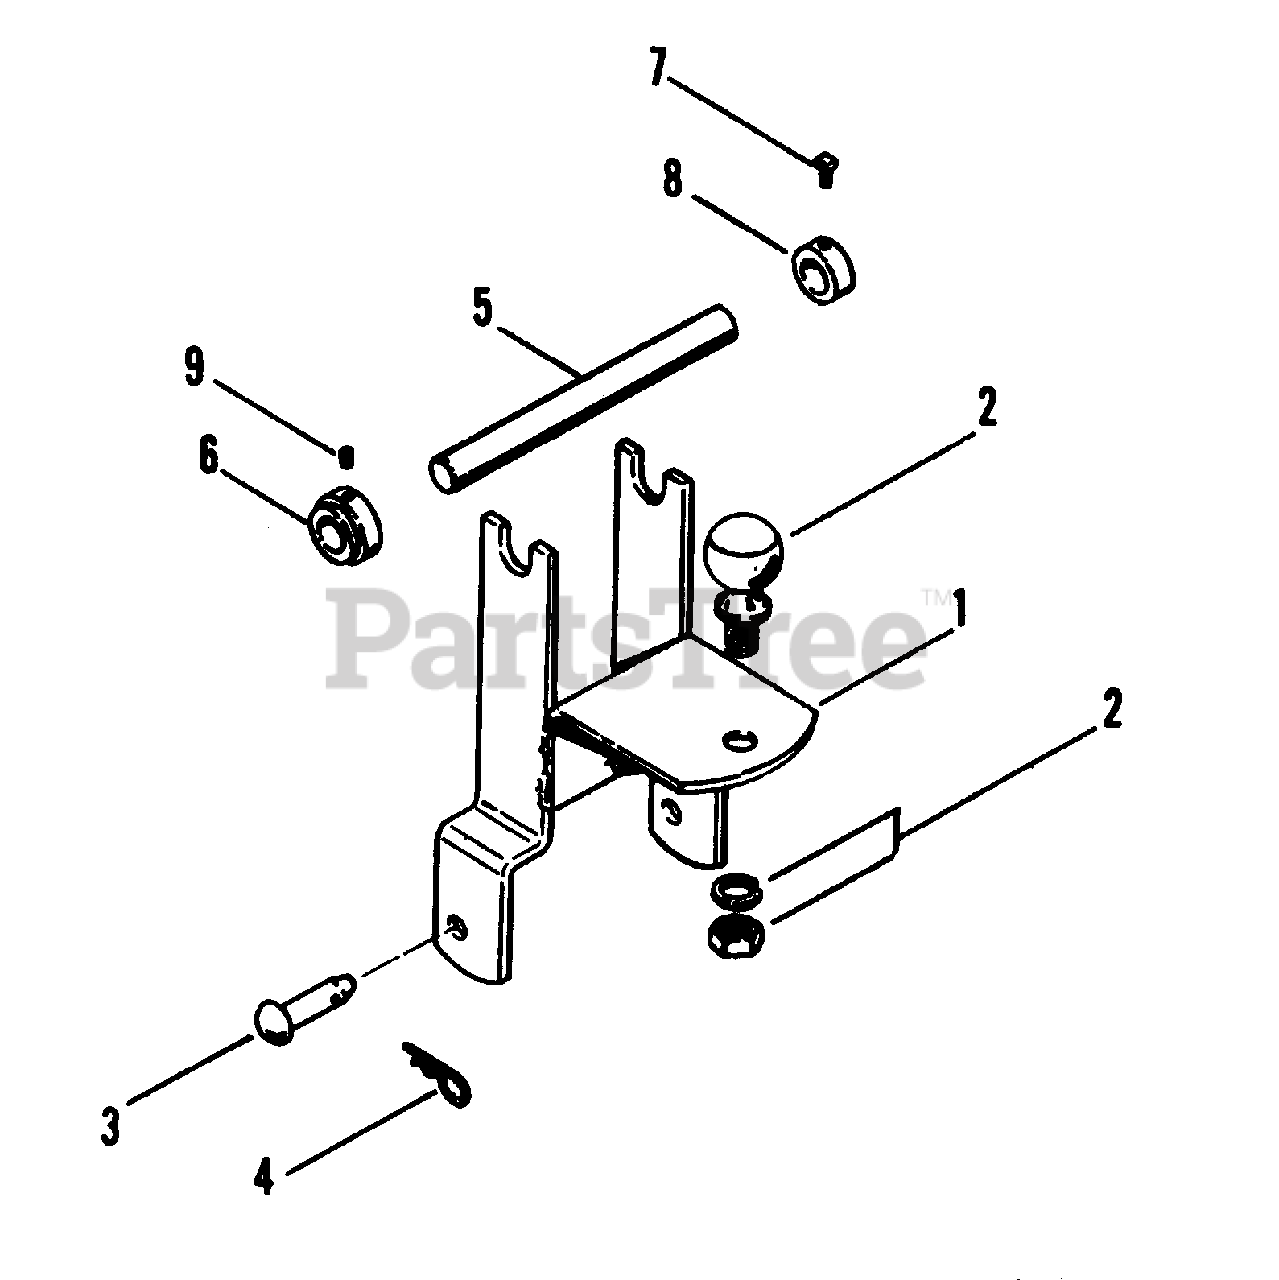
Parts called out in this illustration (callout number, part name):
1	HITCH ASSY, Rear
2	BALL, Hitch
4	CLIP, Spring
5	SHAFT, Lift
6	COLLAR, Set
7	SETSCREW, Sq. Hd., 5/16-18 x 3/8
8	COLLAR, Set
9	SETSCREW, Sq. Hd., 5/16-18 x 5/8
